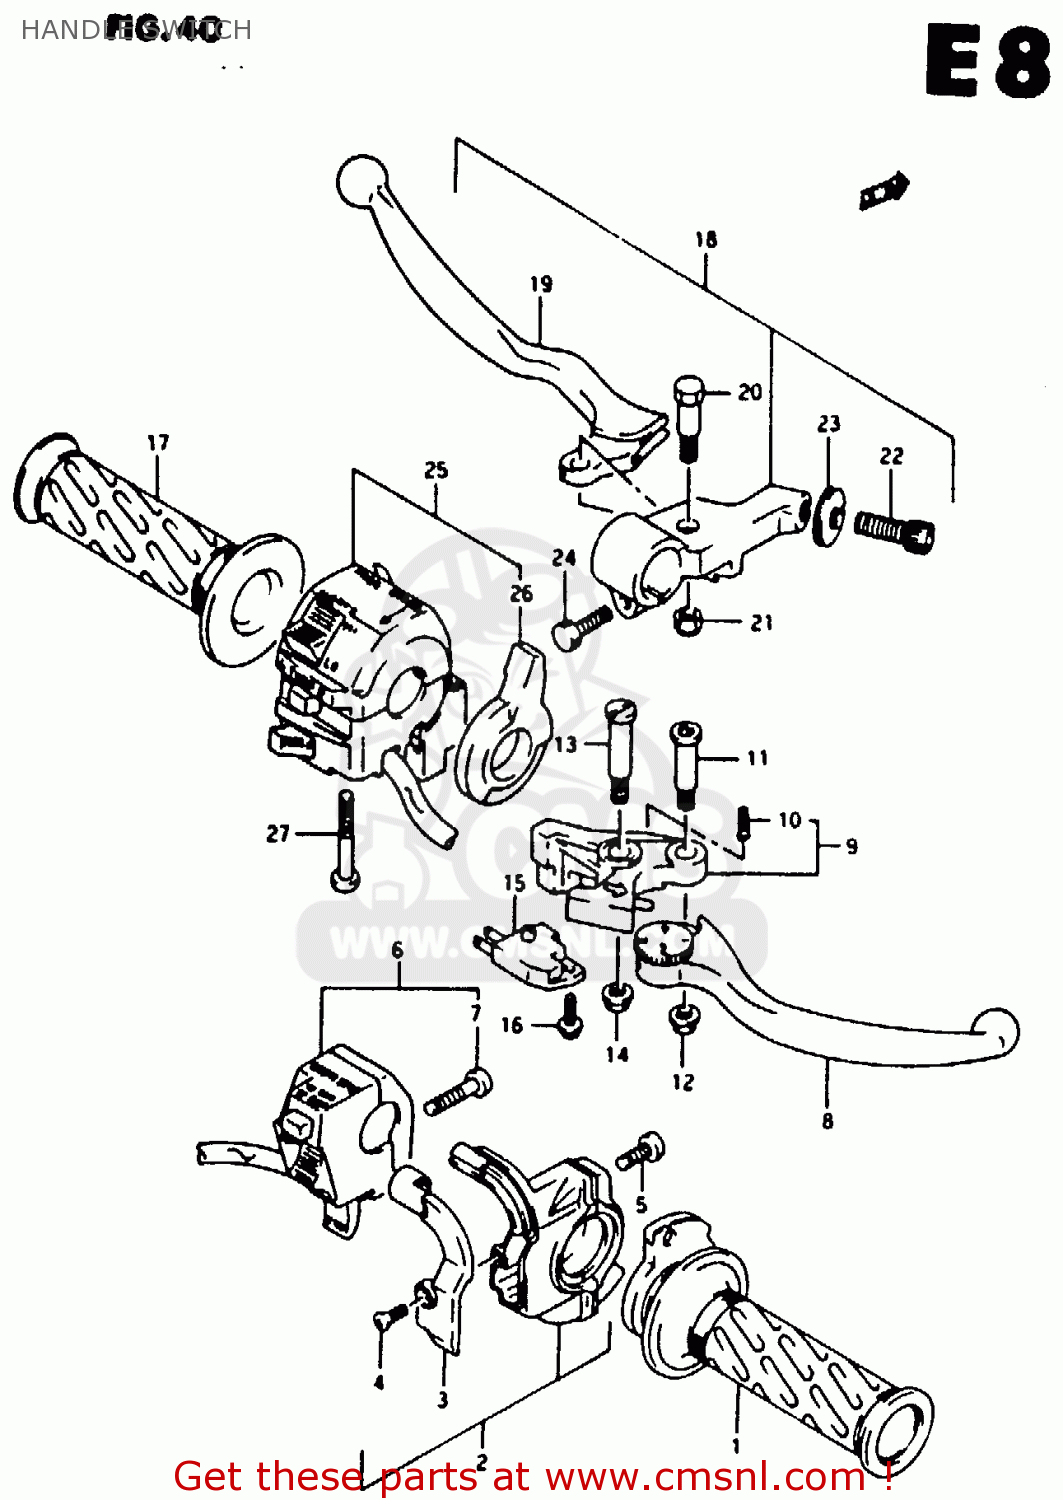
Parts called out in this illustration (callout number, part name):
1	GRIP, THROTTLE
2	CASE ASSY,THROTTLE
3	COVER,THROTTLE CASE
4	SCREW 4X10
5	SCREW
6	SWITCH ASSY,HANDLE,R
7	SCREW, 5X45
8	LEVER,ADJUST
9	KNOCKER
10	SPRING
11	BOLT,LEVER
12	NUT
13	BOLT,LEVER PIVOT
14	NUT 6MM
15	SWITCH ASSEMBLY,STOP
16	SCREW
17	GRIP,LEFT
18	LEVER ASSY,CLUTCH
19	LEVER,CLUTCH
20	BOLT,LEVER
21	NUT
22	ADJUSTER,CABLE
23	NUT,CABLE ADJUSTER
24	BOLT
25	SWITCH ASSEMBLY,HANDLE,LEFT
26	LEVER,CHOKE
27	SCREW, 5X45
